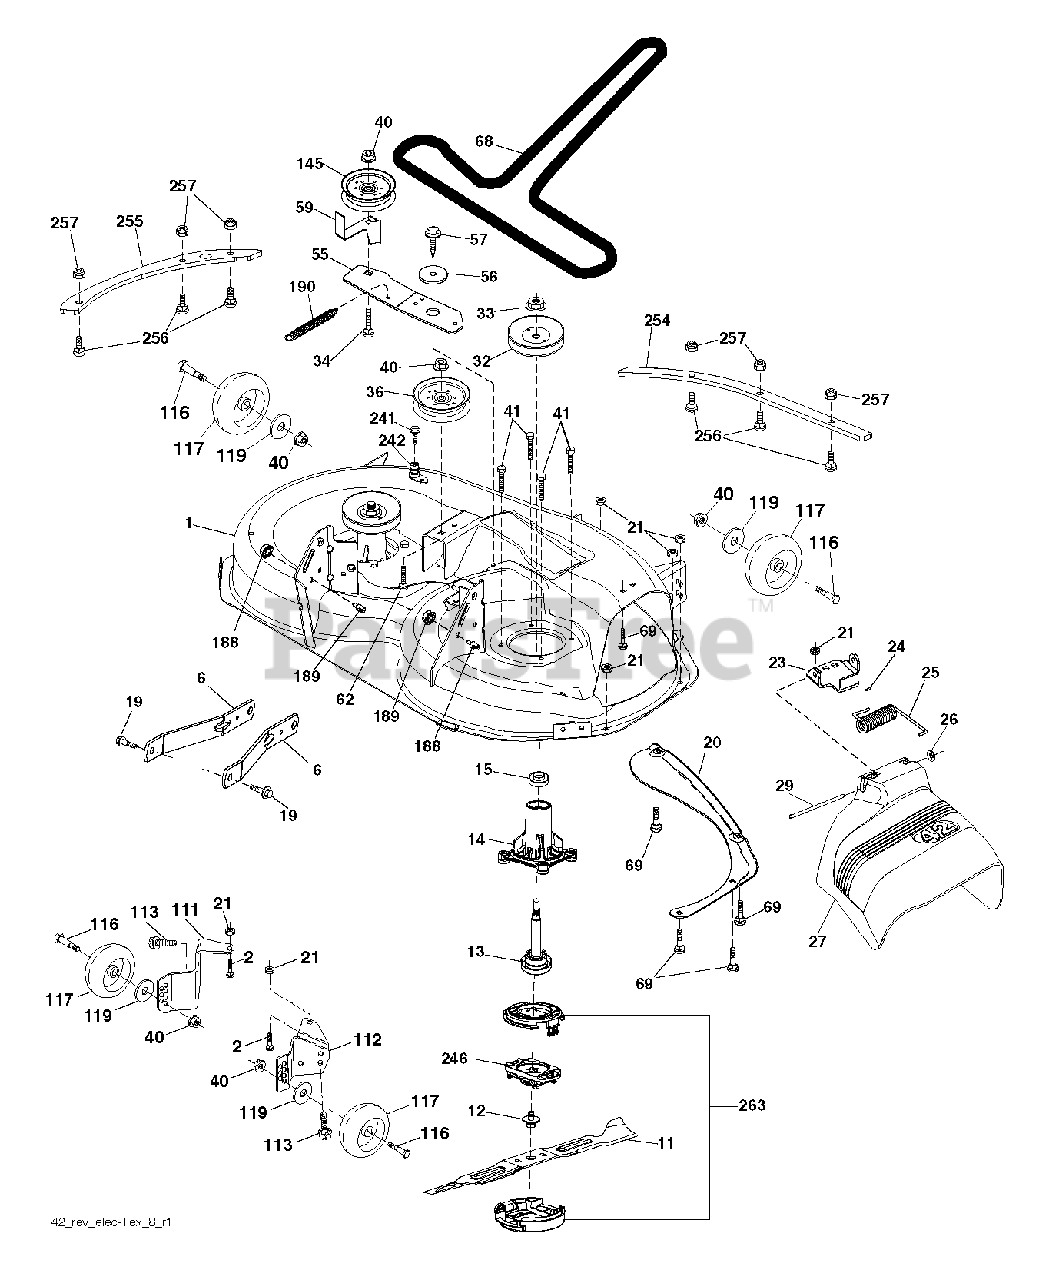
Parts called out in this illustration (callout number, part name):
1	DECK.SVC.42"2GW
2	BOLT 5/16-18 X3/4 ZN/YEL GR 5
6	ARM.SUSPENSION.MOWER.R
11	BLADE.REVOLUTION.42"3IN1.PT43
12	SCREW.SEMS.7/16-20X1.HEX.HEAD
13	SHAFT ASM.REV.TALL.N/GREASEBL
14	HOUSING.MANDREL.REV.TALL.N/GRS
15	BEARING.MANDREL.TOP.EXTENDED
19	BOLT.SHOULDER
20	BAFFLE.VORTEX
21	LOCKNUT
23	BRKT.DEFLECTOR.38"2005+
24	CAP-SLEEVE LT
25	SPRING.TORSION.DEFLECT
26	NUT PUSH M
27	SHIELD.DEFLECTOR.MOWER.42"BLAC
29	ROD.HINGE
32	PULLEY/MANDREL
33	NUT.FLANGE.LOCK.TOP
34	BOLT.3/8-16X1.50
36	PULLEY.IDLER.2006
40	NUT LOCK FLG 3/8-16 UNC
41	BOLT.HEX.WASHR.HED.313-18X1.19
55	IDLER.ARM.42"
56	SPACER.RETAINER
57	SCREW 3/8-16X1
59	GUARD, BELT
68	BELT V SECONDARY
69	BOLT
111	BRKT.WHEEL.GAUGE.LH.42"
112	BRKT.WHEEL.GAUGE.RH.42"
113	BOLT.5/16HEX.WHS.HD
116	BOLT M
117	WHEEL.GAGE.HALF.SPOKED
119	WASHER
145	PULLEY.IDLER.48"PRIMARY
188	STUD.FASTNER.W/ANTI-ROTATE
189	NUT LOCK HEX FLANGE 5/16-18
190	SPRING.MOWER.DRIVE.ELECTRIC
241	SCREW.TT.#10-32X.5.3/8.FLANGE
242	PORT.WASHOUT
246	HOLDER.BLADE.REVOLUTION
254	PLATES.RENFRC.42DECK.PT431FRNT
255	PLATES.RENFRCE.42DECK.X431SIDE
256	RHSNB, 1/4-20 X 1, GR5
257	NUT T
263	CAP.REVOLUTION ASM
